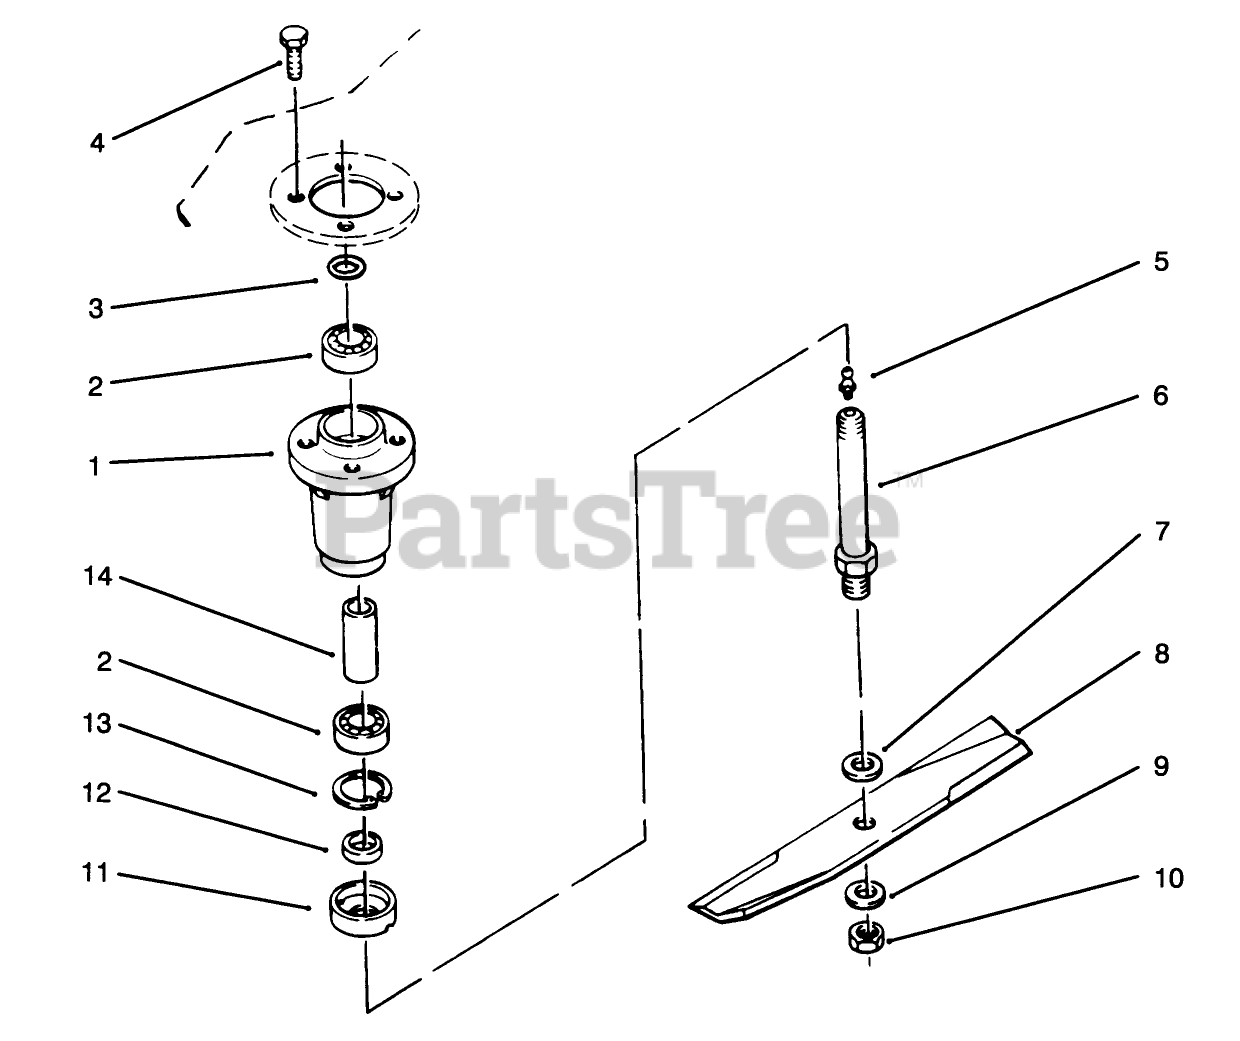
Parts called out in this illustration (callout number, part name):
1	HOUSING-SPINDLE
2	BEARING-BALL
3	O RING
4	SCREW-HH
5	FITTING-GREASE
6	SHAFT-SPINDLE
7	WASHER-FLAT
8	BLADE KIT
9	WASHER-FLAT
10	NUT-JAM
11	CUP-SPINDLE
12	SPACER-BLADE
13	RING-RETAINING
